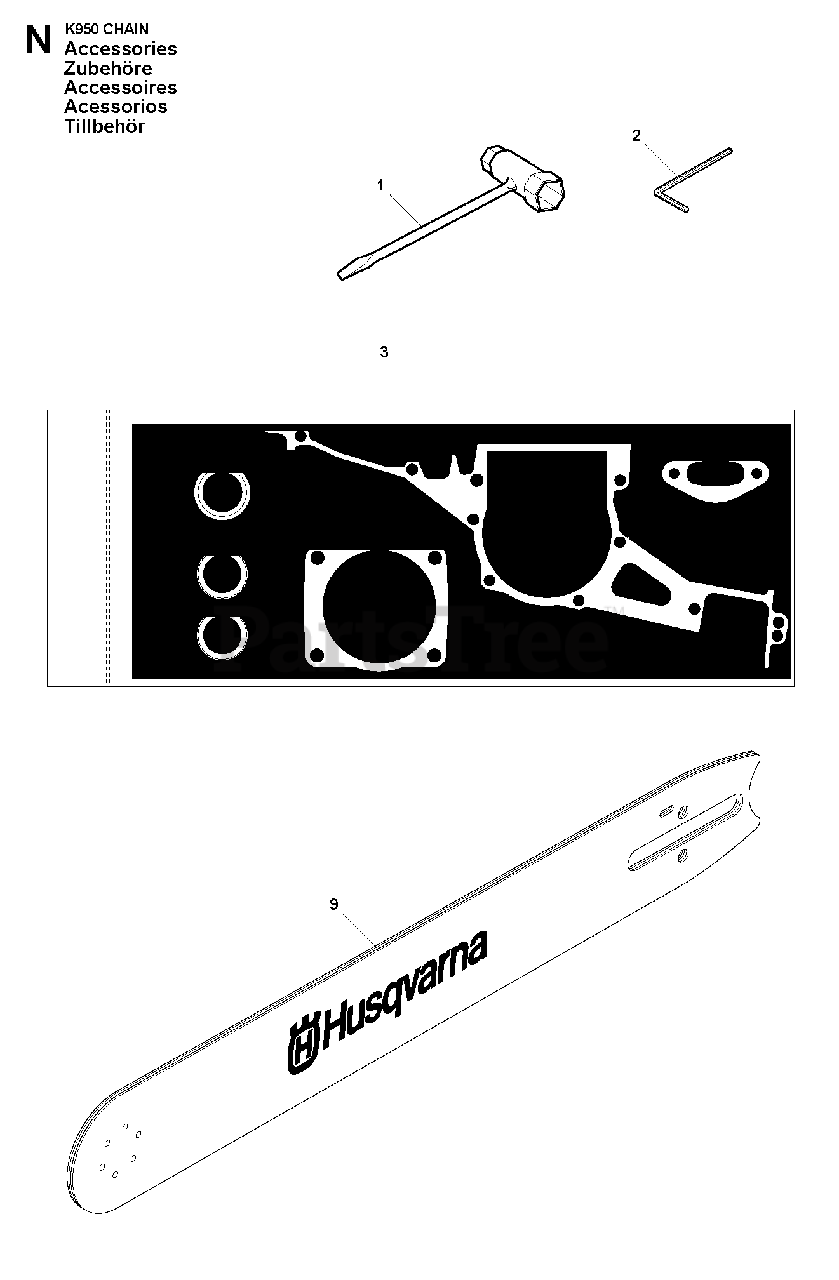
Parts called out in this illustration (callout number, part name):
1	COMBINATION WRENCH13-19
3	GASKET KITIncl. 4, 5, 6, 7, 8
5	SEALING RING
6	CYLINDER BASE GASKET
8	GASKET
